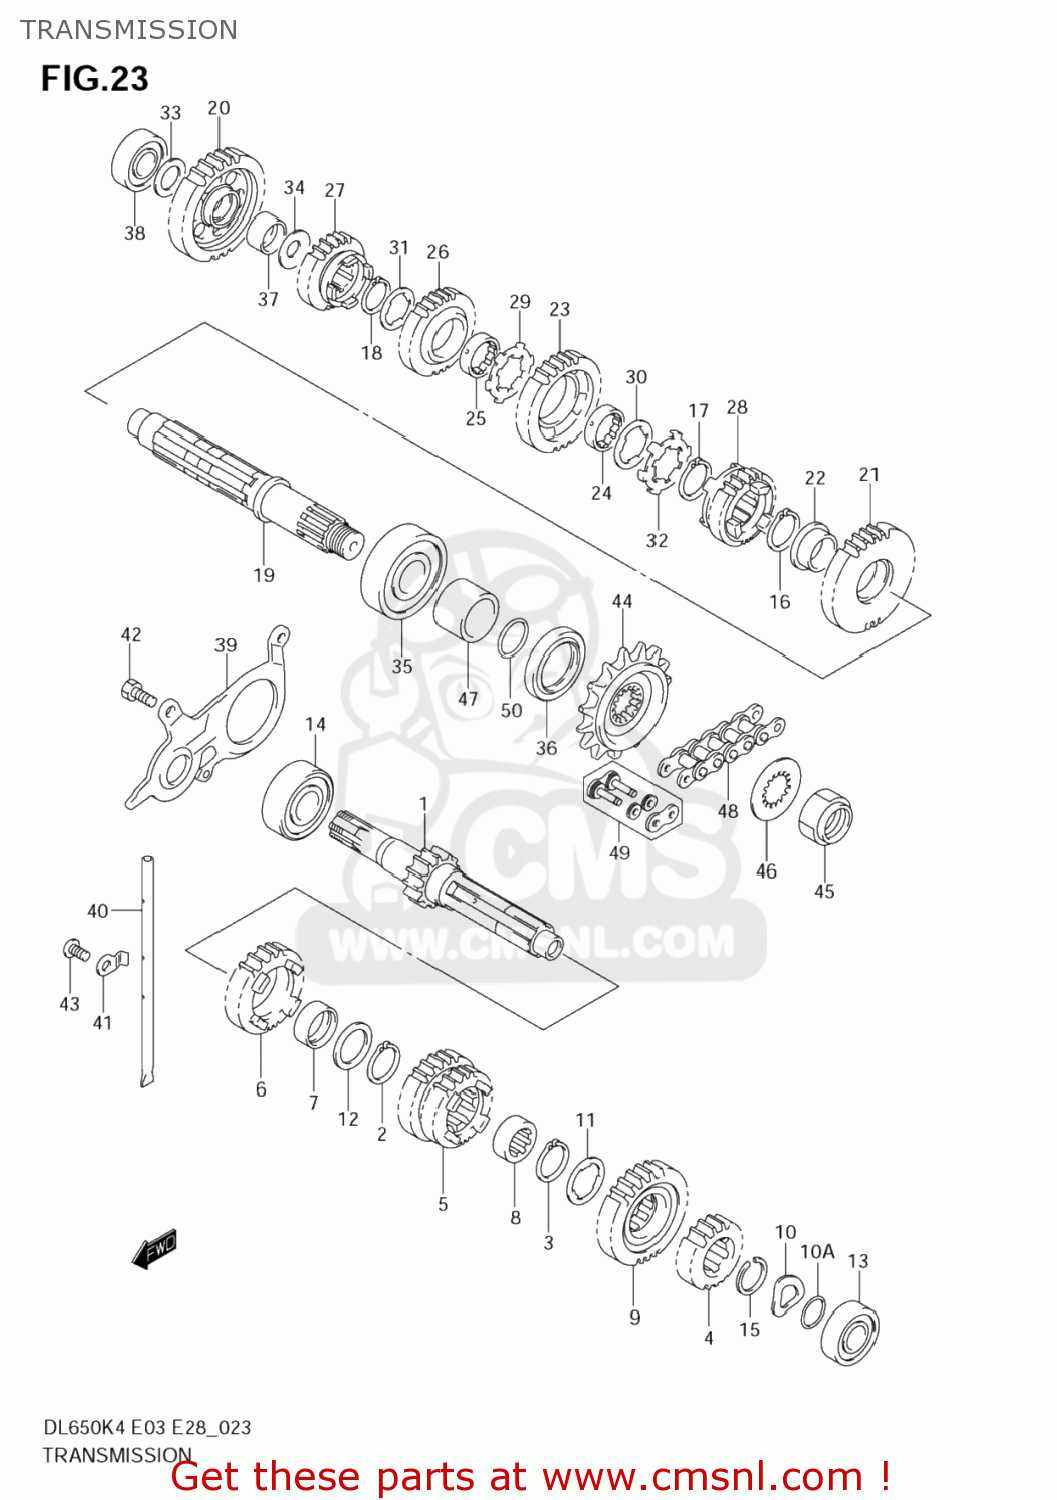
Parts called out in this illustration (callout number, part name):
1	SHAFT,COUNTER
2	CIRCLIP
3	CIRCLIP
4	GEAR,SECOND DRIVE (NT:18)
5	GEAR,3RD & 4TH
6	GEAR,5TH DRIVE(NT:26)
7	BUSH
8	BUSH,6TH DRIVE GEAR
9	GEAR,6TH DRIVE(NT:27)
10	WASHER
10A	O RING(D:1,ID:16.8)
11	WASHER,LOCK
12	SHIM(25X34X1)
13	BEARING(17X40X12)
14	BEARING 20X52X15
15	CIRCLIP
16	CIRCLIP
17	CIRCLIP
18	CIRCLIP
19	SHAFT,DRIVE
20	GEAR,1ST DRIVEN(NT:32)
21	GEAR,SECOND DRIVEN (NT:32)
22	BUSH
23	GEAR,3RD DRIVEN(NT:29)
24	BUSH,DRIVEN GEAR
25	BUSH,DRIVEN GEAR
26	GEAR,4TH DRIVEN(NT:27)
27	GEAR,5TH DRIVEN(NT:25)
28	GEAR,6TH DRIVEN(NT:23)
29	WASHER,LOCK
30	WASHER,LOCK
31	WASHER,LOCK
32	WASHER
33	SHIM(17X28X1)
34	SHIM(20X30X1)
35	BEARING(25X62X17)
36	SEAL,OIL(36X50X6)
37	BUSH(20X24X13)
38	BEARING(17X40X12)
39	RETAINER,DRIVESHAFT O
40	GUIDE,T/M OIL
41	RETAINER,TRANSMISSION OIL
42	BOLT
43	SCREW
44	SPROCKET,ENGINE(NT:15)
45	NUT
46	WASHER,LOCK
47	SPACER,ENGINE SPROCKET
48	CHAIN(DID525V8,116LE)
49	JOINT SET,CHAIN
50	O RING(D:2.4,ID:23.7)
